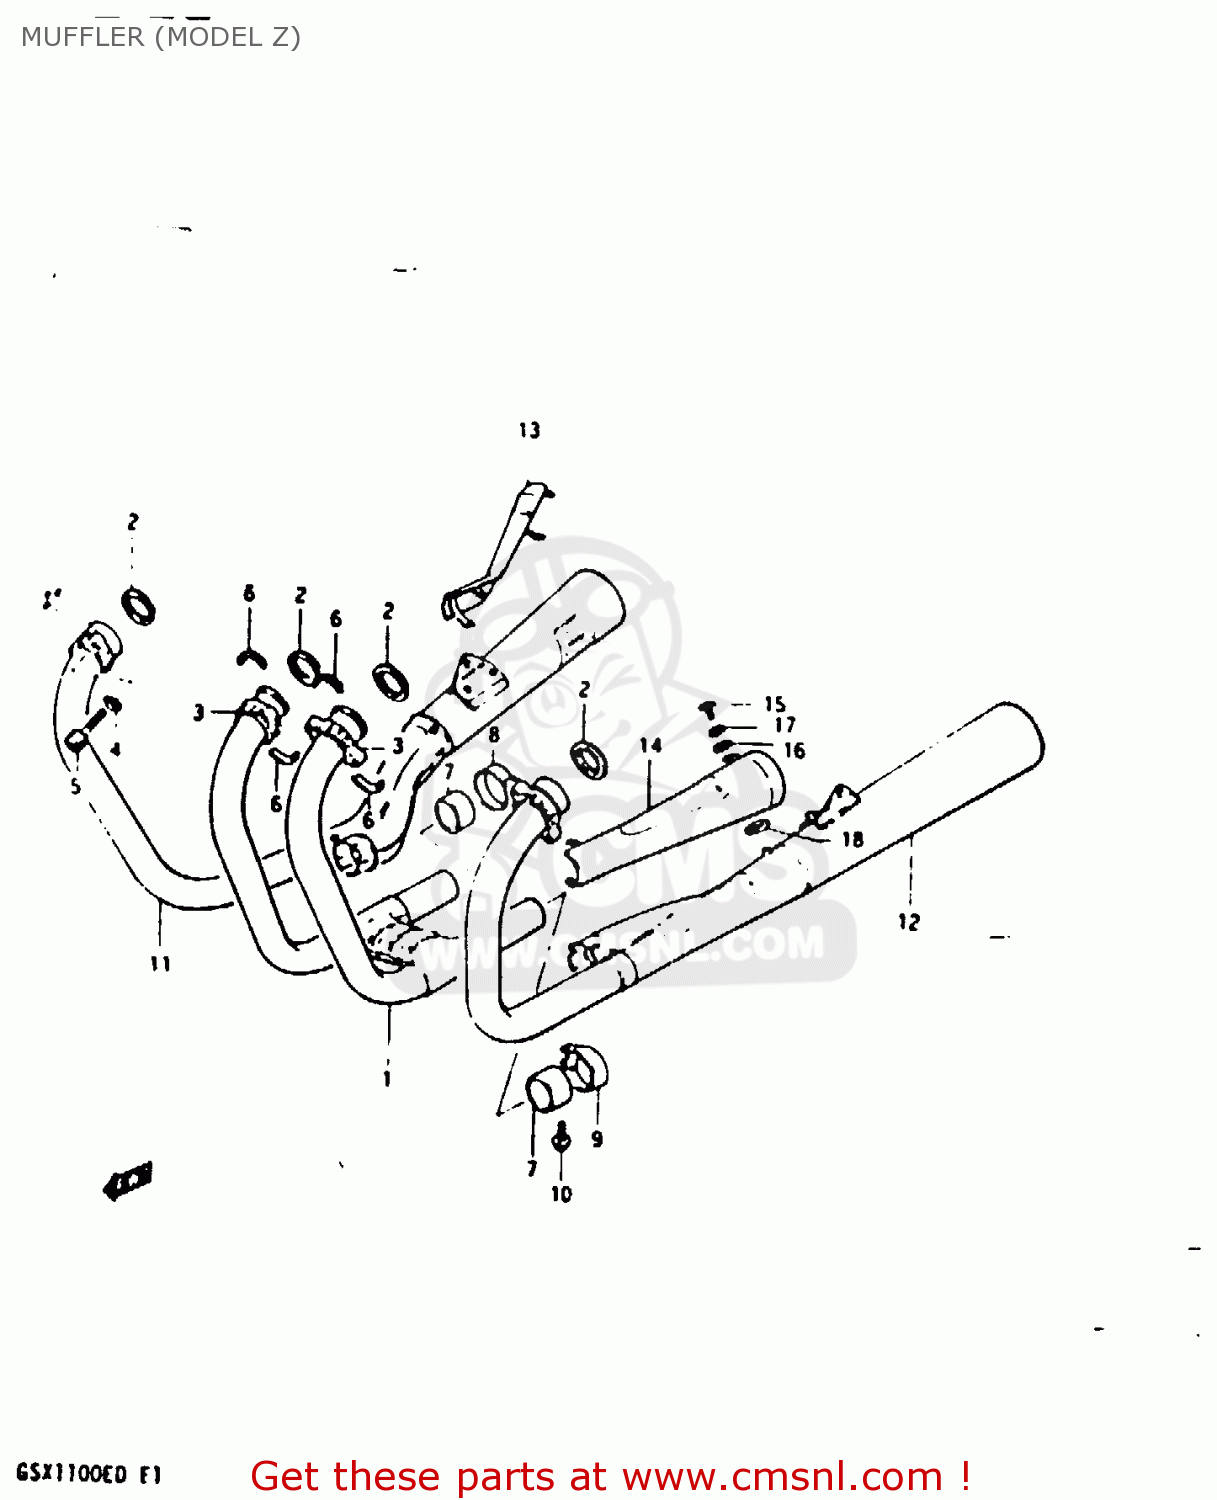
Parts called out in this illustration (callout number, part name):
1	PIPE,EXHAUST,CENTER
2	GASKET,EXHAUST PIPE (NAS)
3	CLAMP(H:21)
4	LOCK WASHER
5	BOLT
6	PLATE,EXHAUST P
7	CONNECTOR,MUFFLER
8	CLAMP,MUFFLER CONNECTOR,R
9	CLAMP,MUFFLER CONNECTOR,L
10	BOLT
11	MUFFLER ASSEMBLY
12	MUFFLER ASSEMBLY
13	COVER,MUFFLER
14	COVER,MUFFLER
15	SCREW
16	WASHER
17	LOCK WASHER
18	GASKET 6.2X12X1.5 (MCA)
